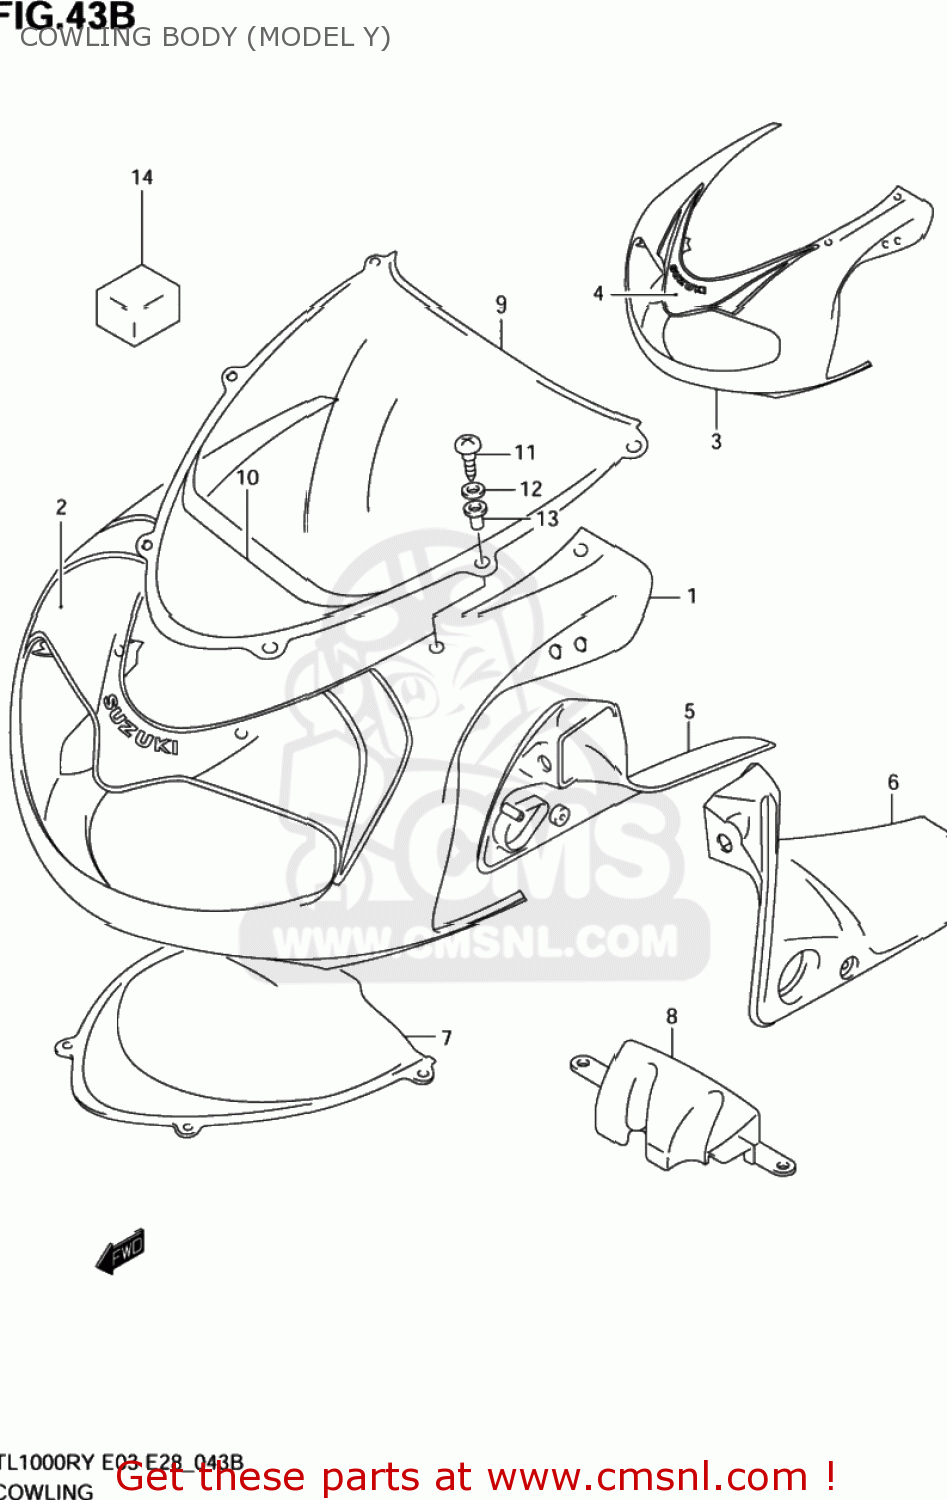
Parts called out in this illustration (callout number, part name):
1	COWLING ASSEMBLY,BODY
2	TAPE,BODY COWL FR
3	COWLING ASSY,BODY
4	TAPE,BODY COWLING,FRONT
5	PANEL,SIDE,R(BLACK)
6	PANEL,SIDE,L(BLACK)
7	COVER,BODY COWLING
8	COVER,COWLING FR LWR
9	WINDSCREEN
10	TAPE,WINDSCREEN
11	SCREW(5X14)
12	WASHER
13	NUT
14	CUSHION,BODY COWLING
